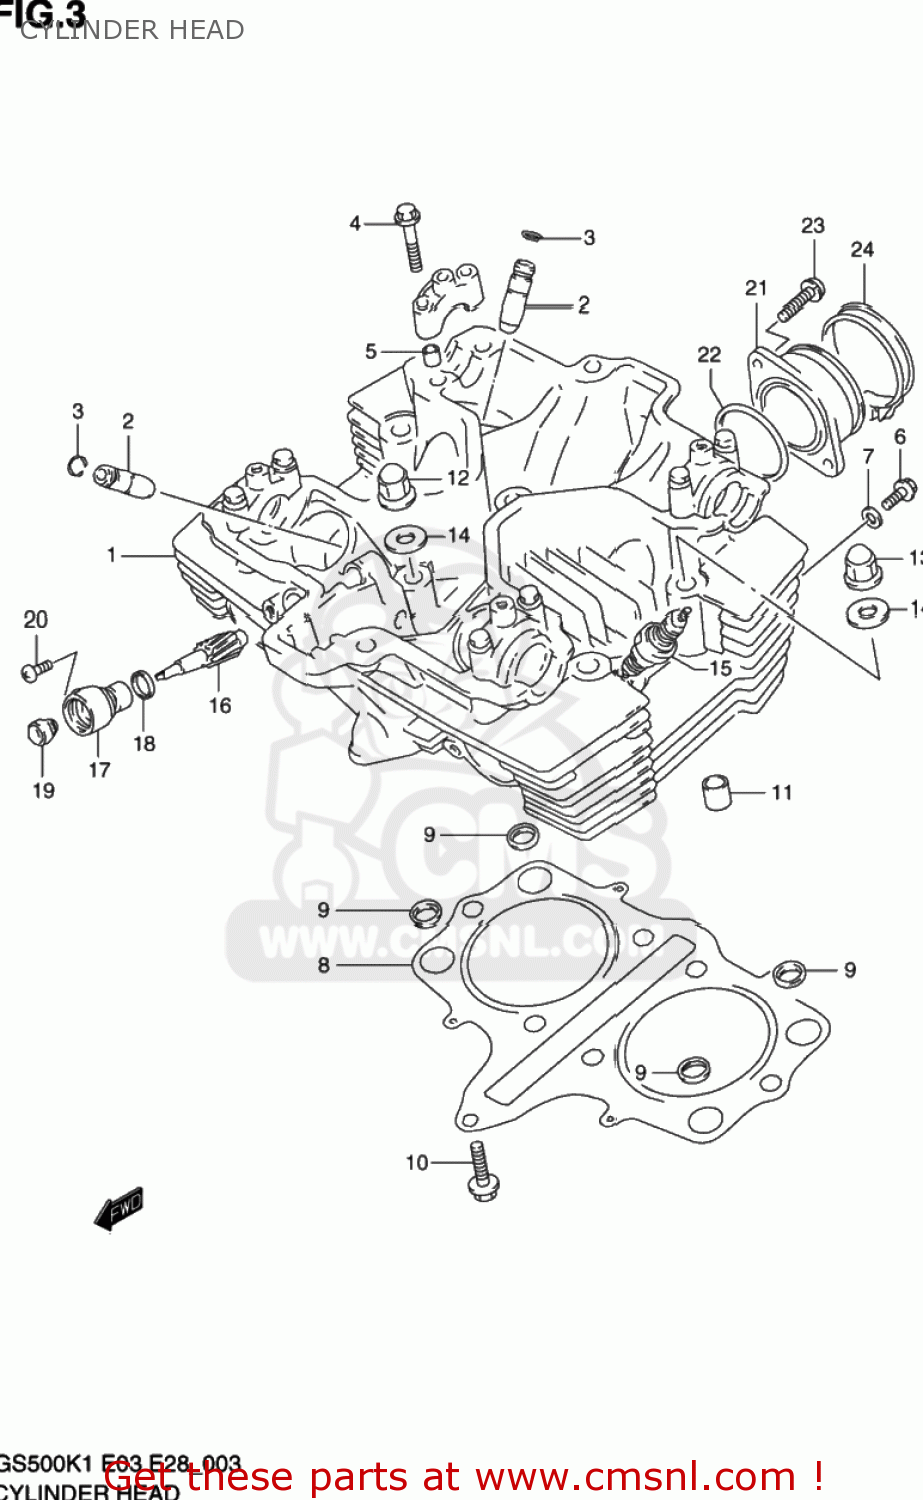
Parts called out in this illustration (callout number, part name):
1	HEAD ASSY,CYLINDER
2	GUIDE,INTAKE VALVE
3	RING,SNAP
4	BOLT(6X39)
5	PIN(6.2X8X11)
6	BOLT
7	GASKET(5.8X13X1.2) (NAS)
8	GASKET,CYLINDER HEAD (NAS)
9	O RING,HEAD GASKET
10	BOLT
11	PIN
12	NUT
13	NUT
14	GASKET(10.2X20X2).3 (NAS)
15	PLUG,SPARK(DPR8EA-9)
16	GEAR,TACHOMETER DRIVEN
17	SLEEVE,TACHOMETER DRIVE GEAR
18	SEAL,TACHOMETER DRIVEN
19	SEAL,OIL(5X12X8)
20	SCREW(5X12)
21	PIPE ASSY,INTAKE
22	O RING(D:2.4,ID:39.7)
23	SCREW
24	CLAMP
